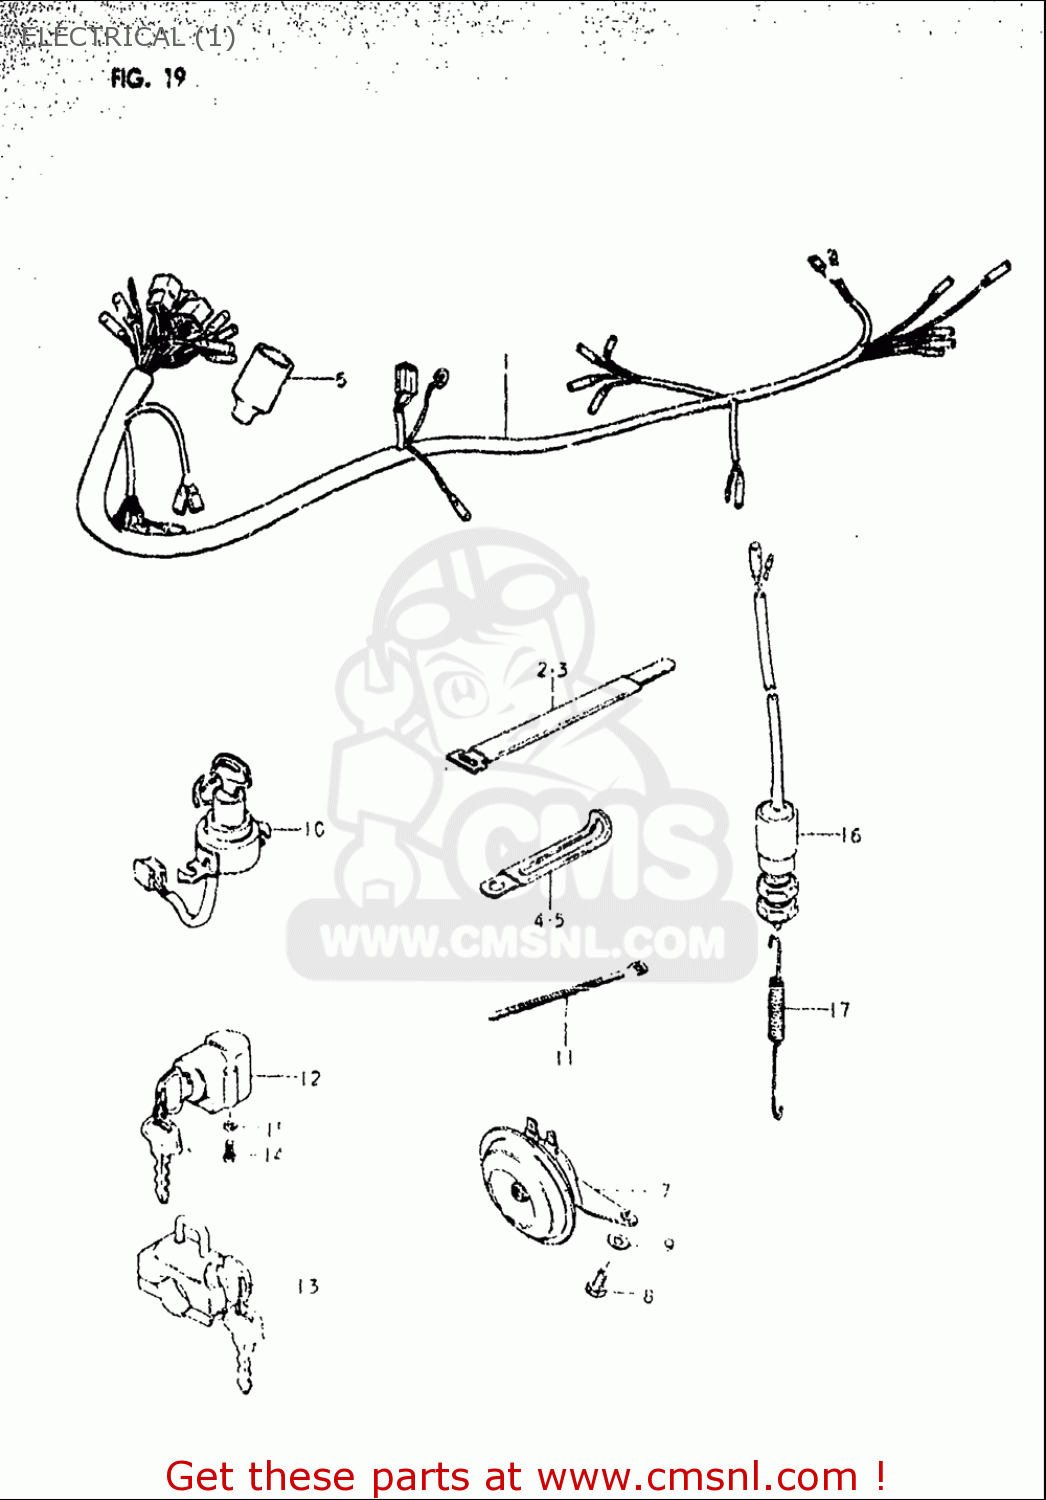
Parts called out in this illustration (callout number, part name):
2	CLAMP
3	CLAMP
4	CLAMP(L:65)
5	CLAMP(L:120)
6	BOOT,WIRING HARNESS
7	HORN ASSY
8	BOLT
9	WASHER
11	CLAMP(L:145)
12	LOCK ASSY,STEERING
13	LOCK ASSY,HELMET
14	SCREW
15	WASHER,LOCK
16	SWITCH ASSY,STOP LAMP
17	SPRING
